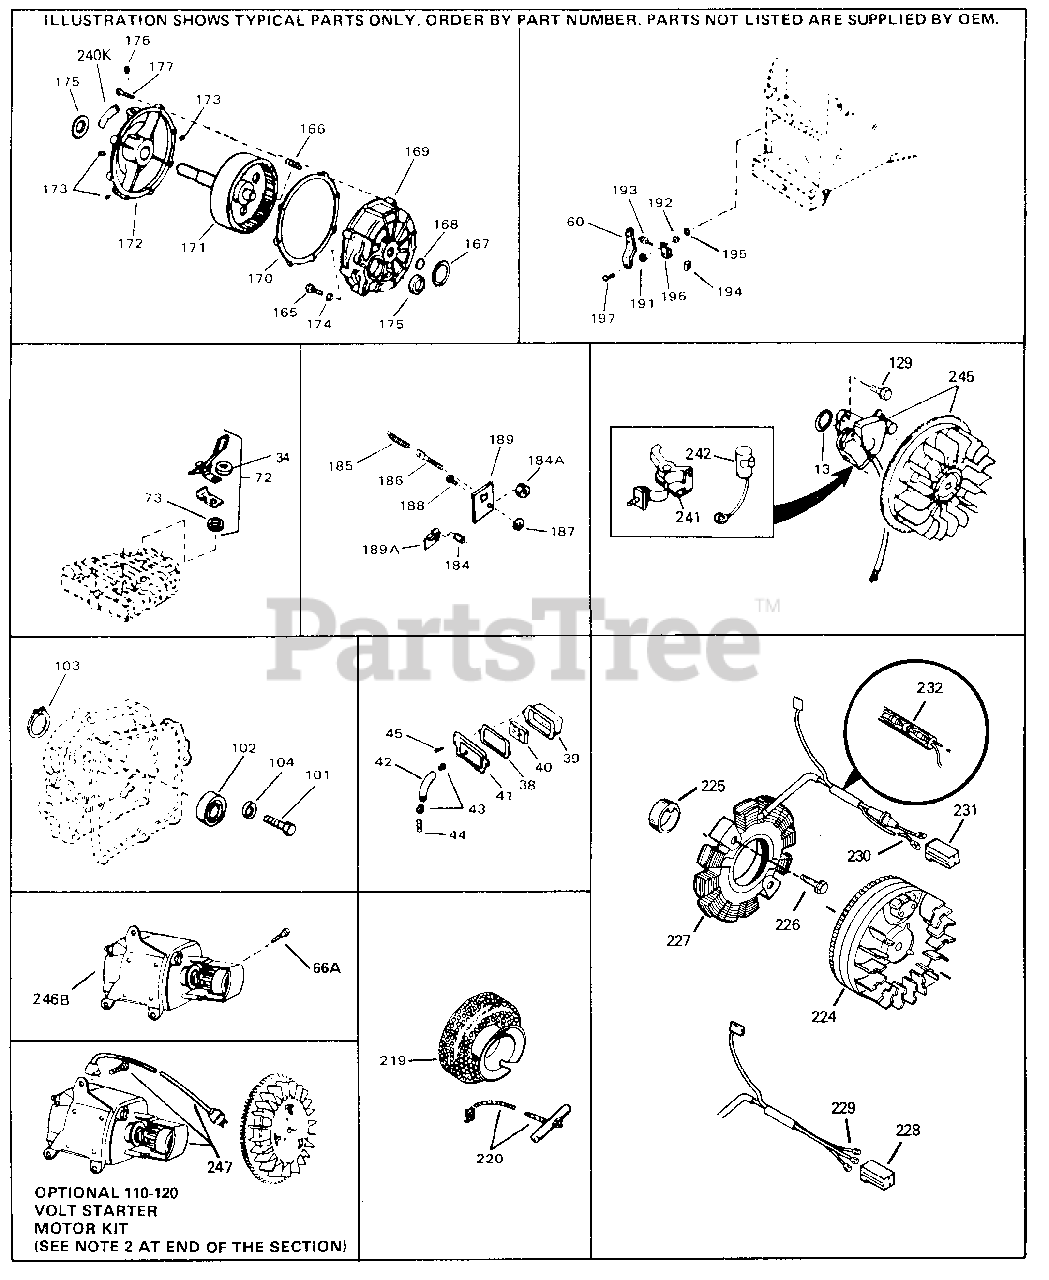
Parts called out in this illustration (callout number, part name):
13	Gasket, Stator
34	Washer (Use as required)
45	Screw, 10-24 x 1/2"
60	Lever, Governor
129	Screw, 1/4-20 x 5/8"
184	Nut, Hex
185	Extension Spring
186	Bolt, Governor spring adj.
187	Washer, Lock
188	Screw, 10-24 x 9/16"
189	Bracket, Governor adj. bolt
197	Screw, 8-32 x 5/16"
219	Pulley, Starter rope
241	Breaker Points (also available in Pac kaged Part #740037B)
242	Condenser (also available in Packaged Part #740037B)
245	Magneto NOTE: The complete magneto i s not available as an assembly. The magneto number is shown for reference purposes only. Order component part sindividually, as shown in partslist. (Refer to Division 5, Section B, pag e 35 for breakdown)
247	Starter Motor Kit (110-120 Volt) This 110-120 volt starter motor kit may h ave been added to this engine. It can be added only if cylinder hasdrilled and tapped starter mounting bosses a nd a ring gear flywheel. Refer to se rvice number stamped on e
